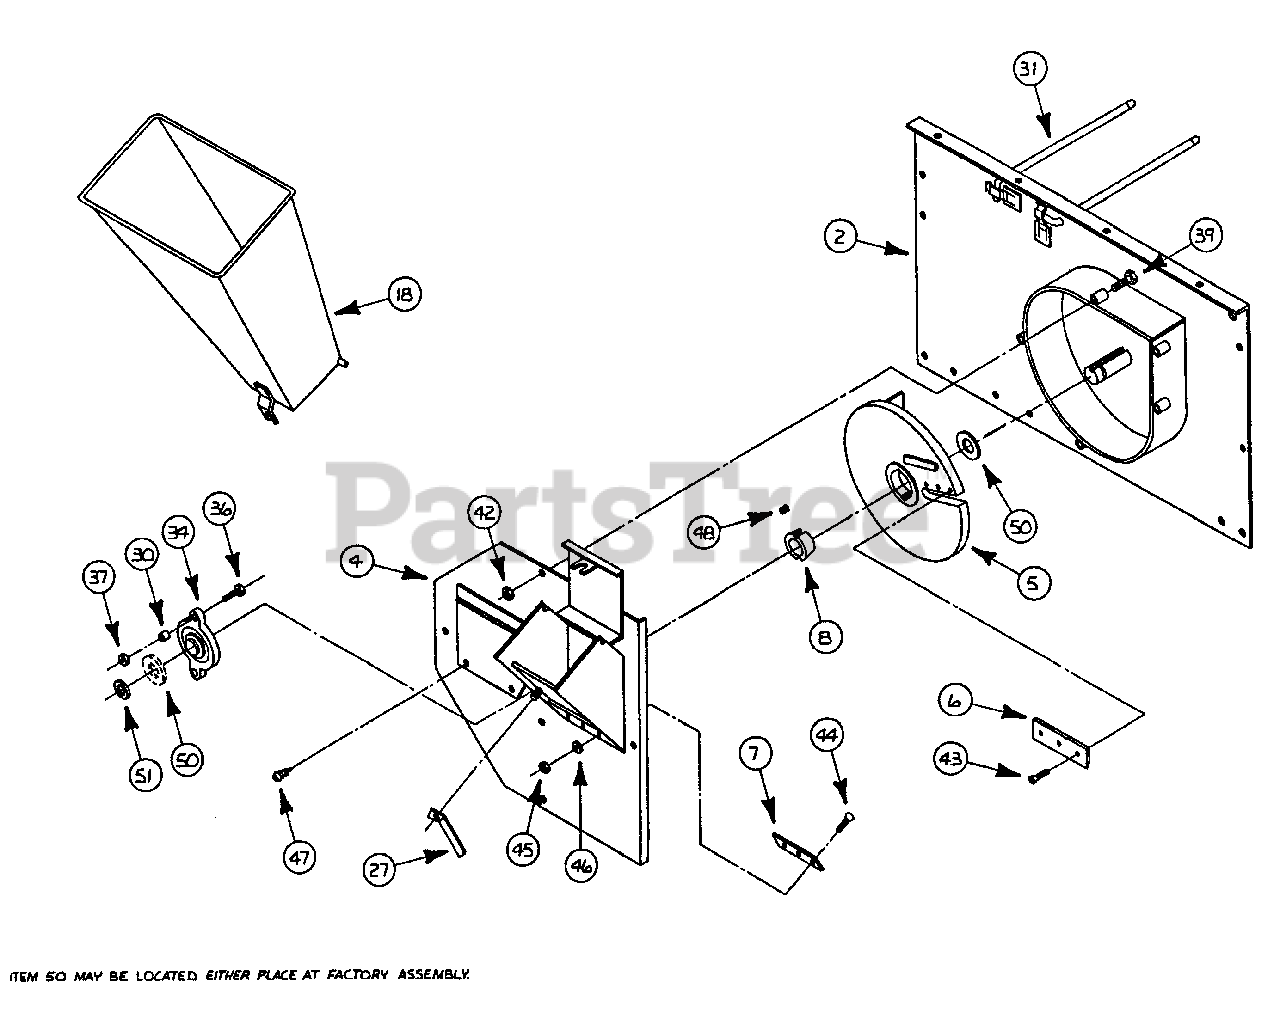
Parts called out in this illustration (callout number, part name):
2	Left Side Plate
4	Chipper Side Plate
5	Chipper Disc
6	Knife
7	Wear Plate
8	Bushing 1-3/16
18	Chipper Hopper
27	Hopper Locking Handle
30	Bushing
31	Screen and Baffle Rod
34	Bearing Left Side
36	3/8-16 x 1 Hex Hd. Cap Screw GR 5 Blk.
37	3/8-16 Grip-Co Lock Nut
39	5/16-18 x 1-1/4 Hex Hd. Cap Screw GR 5
42	5/16-18 Grip-Co Lock Nut
43	5/16-18 x 3/4 Flat Hd. Socket Cap Screw Blk.
44	1/4-20 x 1 Flat Hd. Socket Cap Screw Blk.
45	1/4-20 Flex Lock Nut
46	1/4 Flatwasher
47	6-32 x 3/8 Sheet Metal Screw
48	3/8-16 x 5/8 Set Screw
50	1-3/16 Flatwasher
51	Retaining Ring
